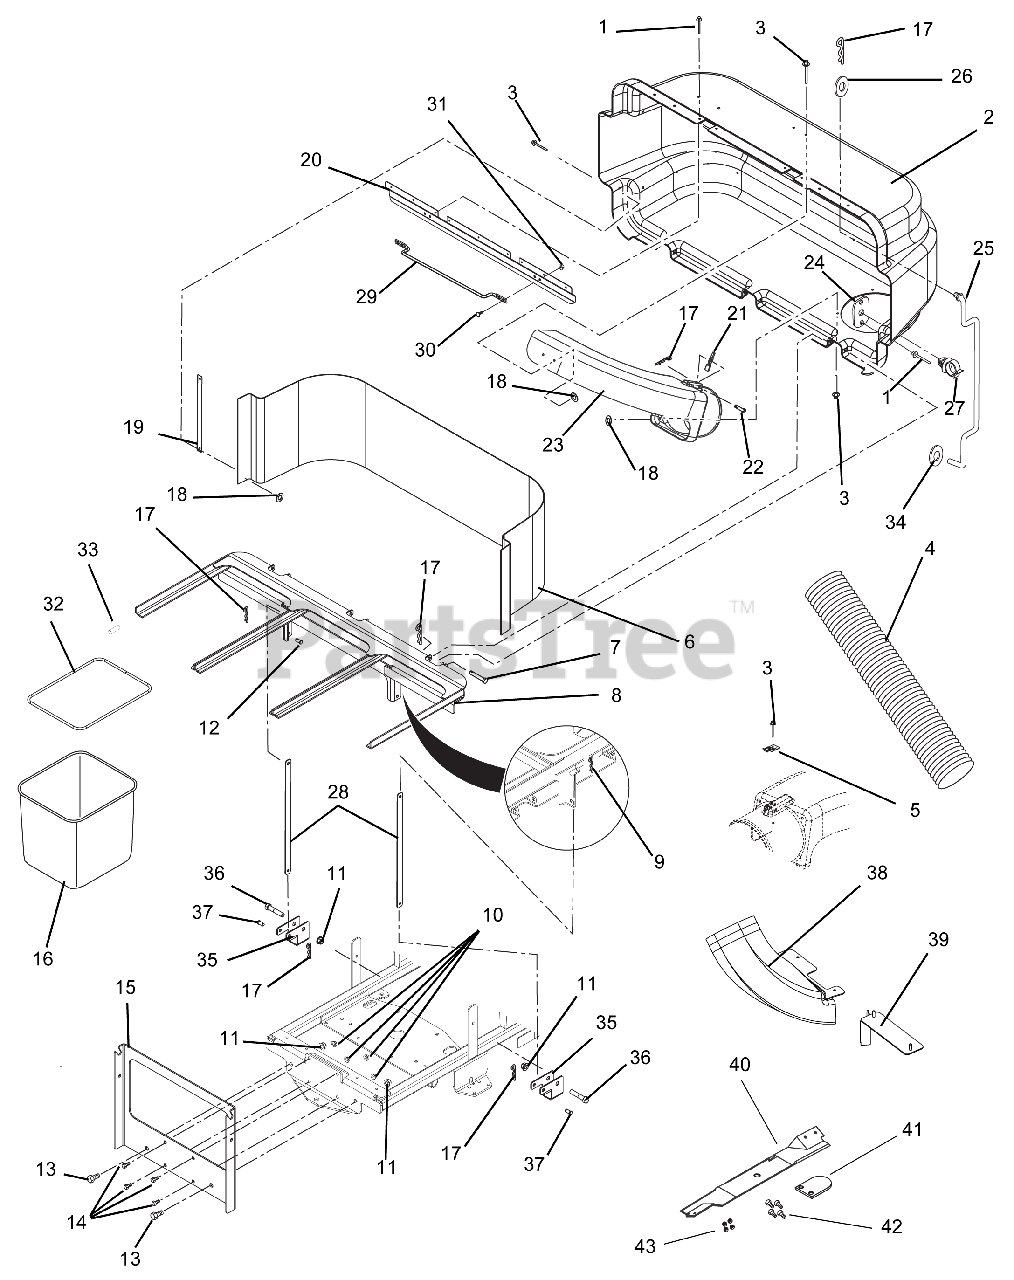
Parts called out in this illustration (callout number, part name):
1	RVT-POP .187X.402 DOME ST
2	BAGGER COVER W/DECAL
3	RVT-POP .187X.375
4	HOSE, FLEXIBLE-47"
5	THUMB LATCH
6	SCREEN, BAGGER
7	PIN-CLEV .371X3.25 YWZC
8	WMT, BAGGER FRAME
9	PIN, HAIR, EXT - #16 YWZC
10	@NUT-LK-NYL-FLG .38-16 YWZC
11	@NUT-LK-NYL-FLG .50-13 YWZC
12	PIN-CLEV .38X.75 YWZC
13	@BLT-HEX .50-13X1.00 GR5 YWZC
14	@BLT-HEX .38-16X1.00 GR5 YWZC
15	MNT, REAR BAGGER
16	BAG, ZOOM MESH
17	PIN-HAIR, ENDRIES #25 YWZC
18	@WSHR-FL-STL.219X.50X.049 YWZC
19	STRAP,COVER
20	LATCH, BAGGER (ZOOM)
21	INDICATOR, FLOW
22	PIN-CLEV .309 X 1.625 YWZC
23	BOOT,UPPER
24	PLATE, ROD CLIP
25	PROP-ROD, BAGGER
26	@WSHR-FL-STL.406X.812X.065 YWZ
27	CLIP-.38
28	STRAP, REINF.
29	BAGGER HANDLE
30	@BLT-RDHDSQNK .25-20X.75 G5YZ
31	@NUT-LK-TOP-FLG .25-20 YWZC
32	FRAME, ZOOM BAG
33	HOSE, .38 X.50 X 3.00 VINYL
34	RETAINER, .38 PUSH-ON
35	CLAMP, ZOOM BAGGER MNT
36	@BLT-HEX .50-13X2.75 GR5 YWZC
37	PIN, CLEV .371 X 2.12 YZ
38	ASSY, 34" BAGGER BOOT
39	WELDMENT, 34" BAGGER MOUNT
40	BLADE, 17.38X2.5X.204 W/HOLES
41	VANE, BLADE
42	BLT-HEX .31-24X.75 GR8 YWZC
43	NUT-CTRLK .31-24 YWZC
